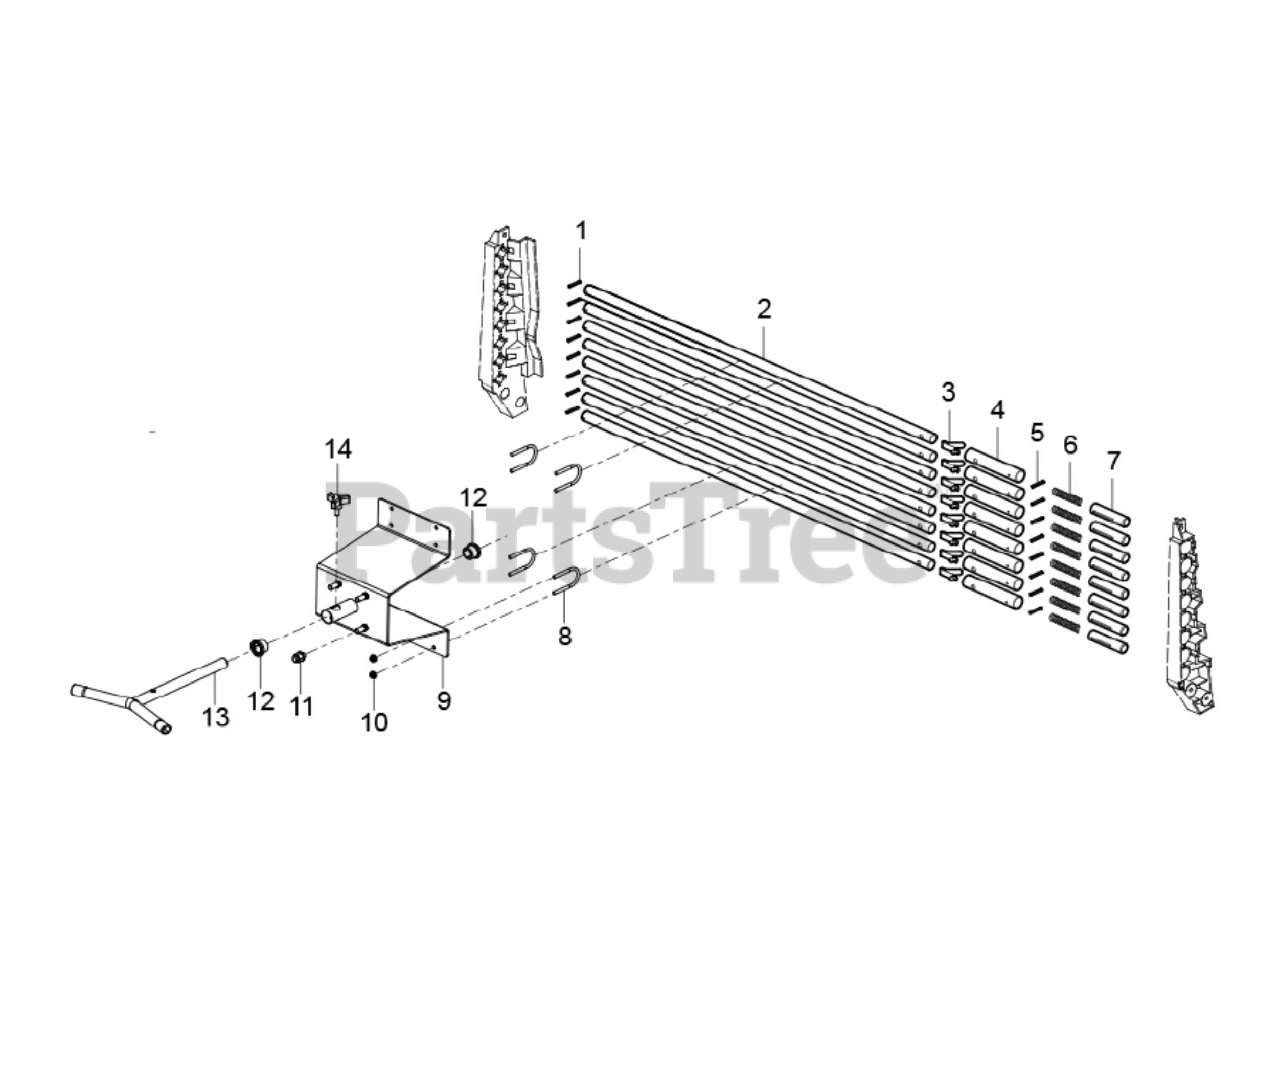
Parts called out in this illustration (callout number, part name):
1	PIN SPRING 3.4X10
2	REAR TUBE ASSEMBLYI
3	SPRING DOWEL
4	REAR TUBE CONNECTOR
5	PIN SPRING 3.4X10
6	PRESSURE SPRING K
7	REAR TUBE ASSEMBLYII
8	U-SHAPED CLIP
9	SPARE TIRE BRACKET
10	LOCK NUT M8
11	TAPER NUT M10X1.25
12	BUSH 22X28
13	TIRE LOCK
14	LOCK HANDLE
